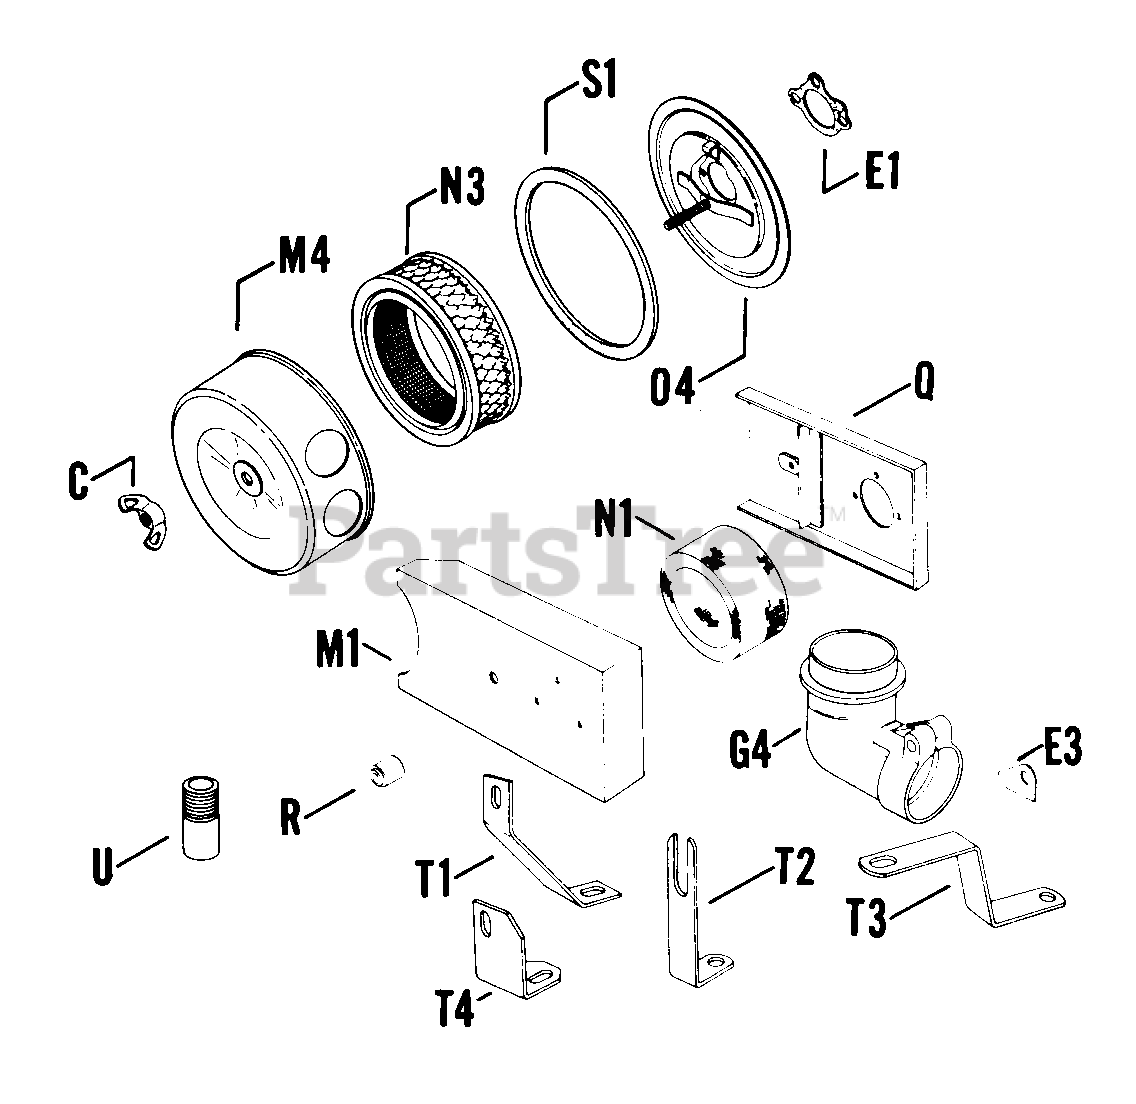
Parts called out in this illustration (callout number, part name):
C	NUT, WING 1/4-20 USE 25 100 15-S
N3	AIR FILTER/PRE-CLEANER KIT USE 25 883 03-S1
T1	BRACE, AIR CLEANER - DISC.
